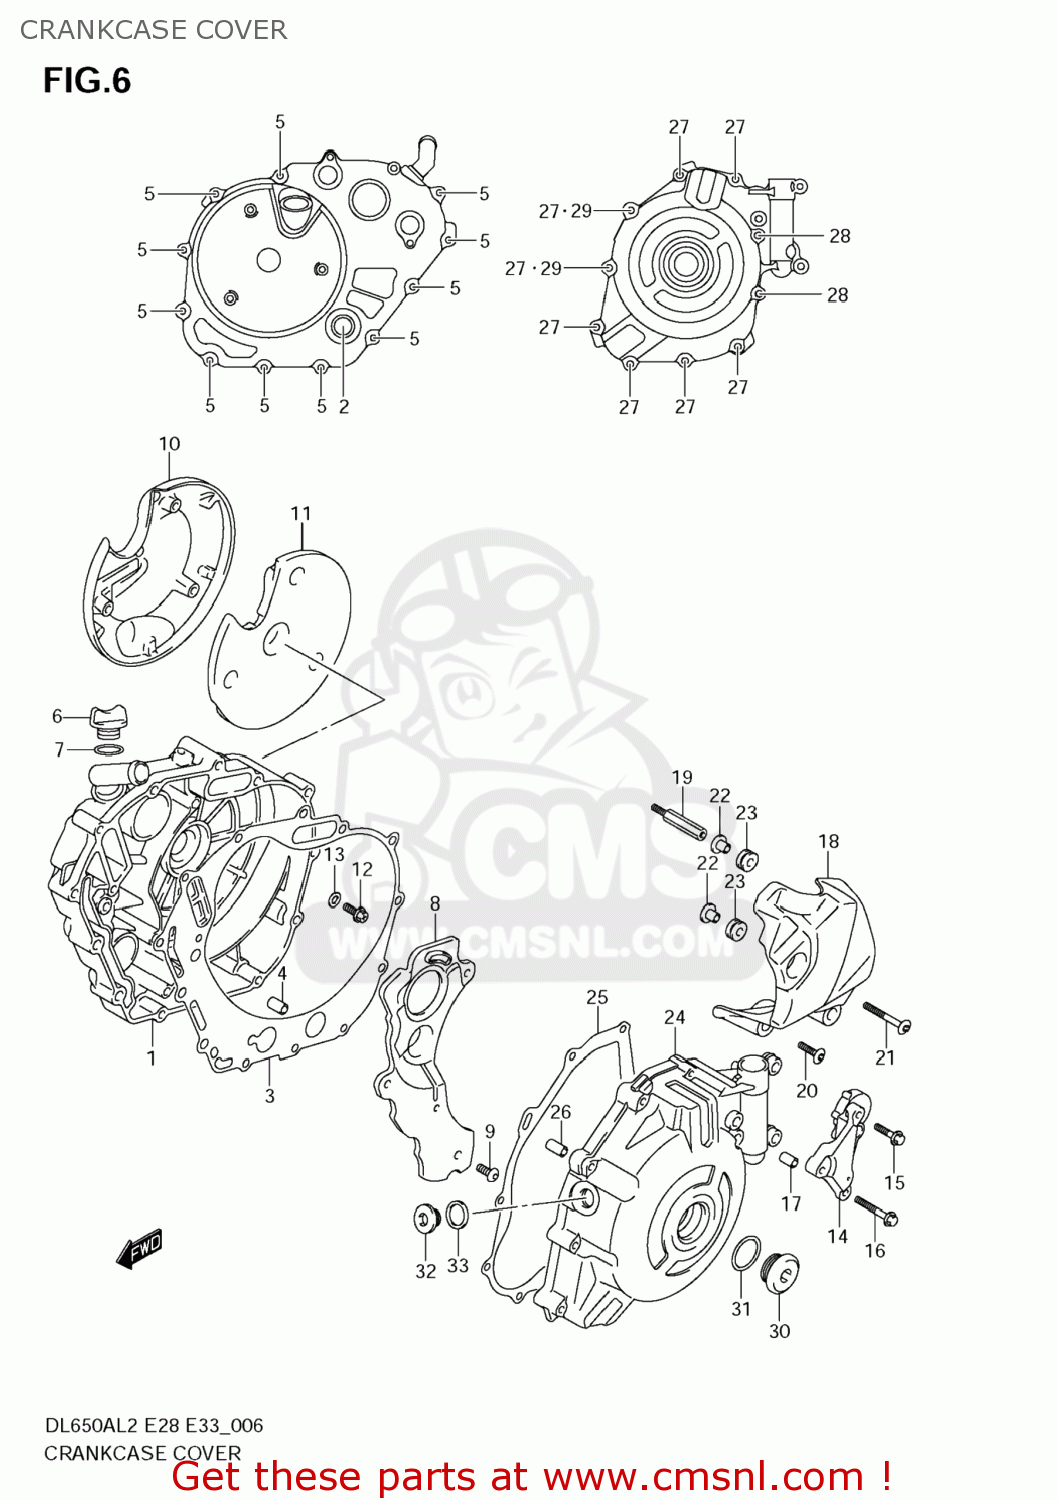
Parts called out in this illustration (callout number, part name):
1	COVER,CLUTCH
2	LENS,OIL LEVEL CHECK
3	GASKET,CLUTCH COVER (NAS)
4	PIN
5	BOLT(6X35)
6	PLUG,ENGINE OIL FILLER
7	O RING(D:3.1,ID:16.8)
8	SEPARATOR,OIL
9	BOLT(6X12)
10	COVER,CLUTCH OUTER
11	DAMPER,CLUTCH OUTER COVER
12	BOLT
13	GASKET(5.8X13X1.2) (NAS)
14	COVER,ENGINE SPROCKET INNER
15	BOLT
16	BOLT
17	PIN
18	COVER,ENGINE SPROCKET OUTER
19	BOLT,SEC DRIVE UNIT COVER
20	SCREW(6X20)
21	SCREW(6X40)
22	WASHER
23	CUSHION
24	COVER,MAGNETO
25	GASKET,MAGNETO COVER (NAS)
26	PIN
27	BOLT(6X35)
28	BOLT(6X65)
29	GASKET(5.8X13X1.2) (NAS)
30	PLUG(26X9)
31	O RING(D:3.1,ID:22.7)
32	PLUG,16X8
33	GASKET(16X22X2) (NAS)
